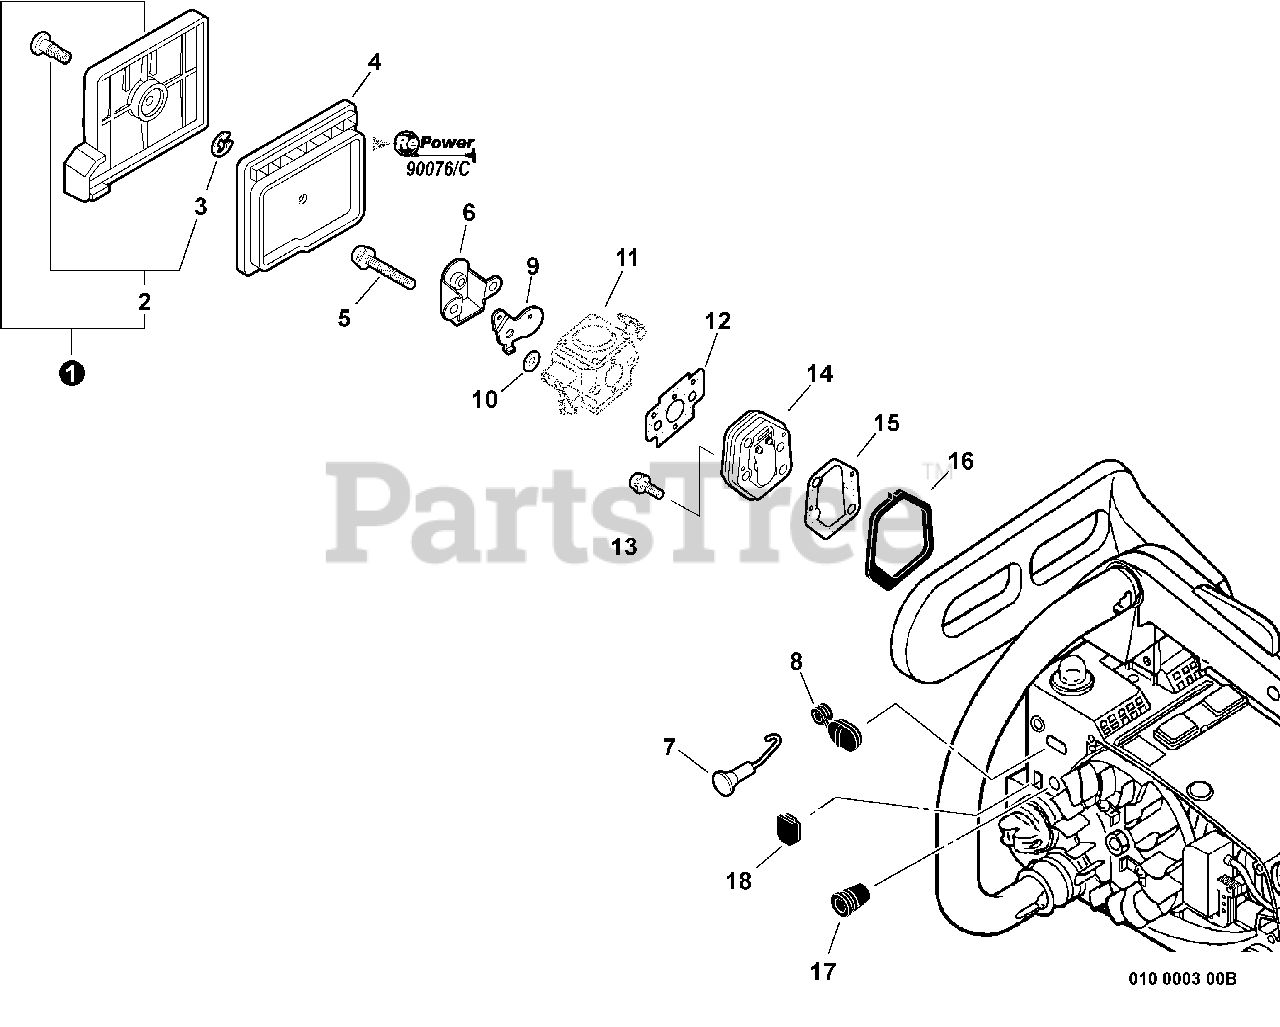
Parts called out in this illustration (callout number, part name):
1	COVER ASSY, AIR FILTER
2	THUMBSCREW
3	E-RING 4
4	FILTER, AIR
5	SCREW 5×45
6	PLATE, PREVENT
7	ROD, CHOKE
8	GROMMET, CHOKE
9	SHUTTER, CHOKE
10	WASHER 5.5×8×0.8
11	CARBURETOR
12	GASKET, INTAKE
13	SCREW 5×18
14	INSULATOR KIT
15	GASKET, INTAKE
16	SEAL, INTAKE
17	GROMMET, IDLE
19	TUNE-UP KIT
